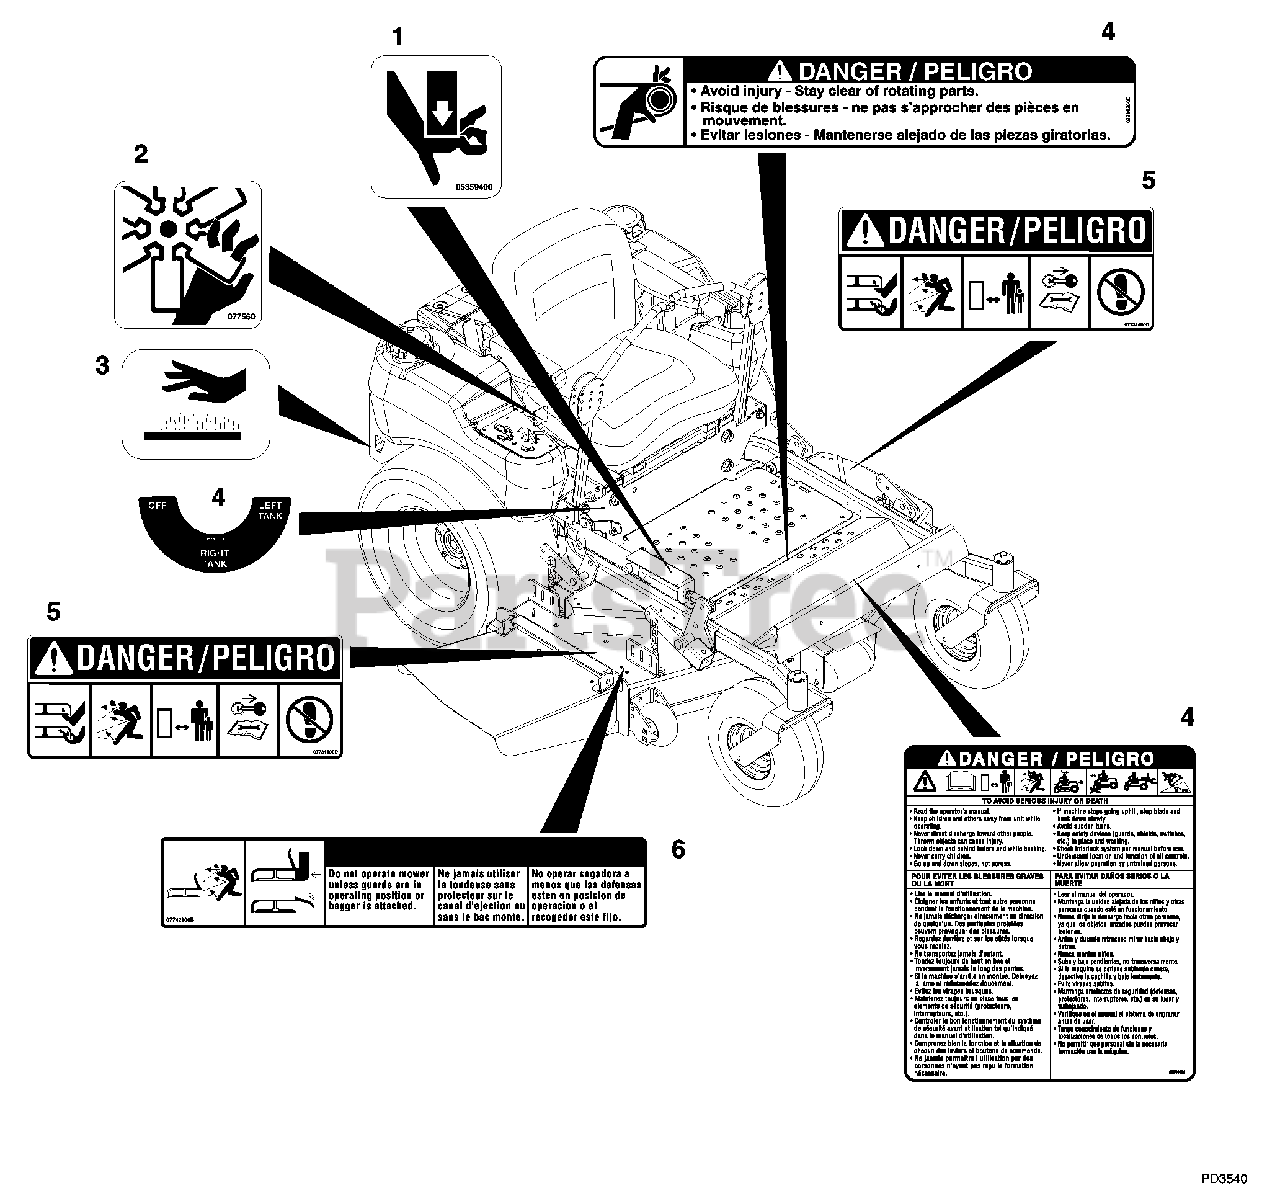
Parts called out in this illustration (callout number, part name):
1	Decal, Pinch Point
2	Decal, Danger Fan
3	Decal, Hot Surface
4	Set, Decal-Common Danger/Fuel
5	Decal, Mower Pan Head Danger
6	Decal, Warning
